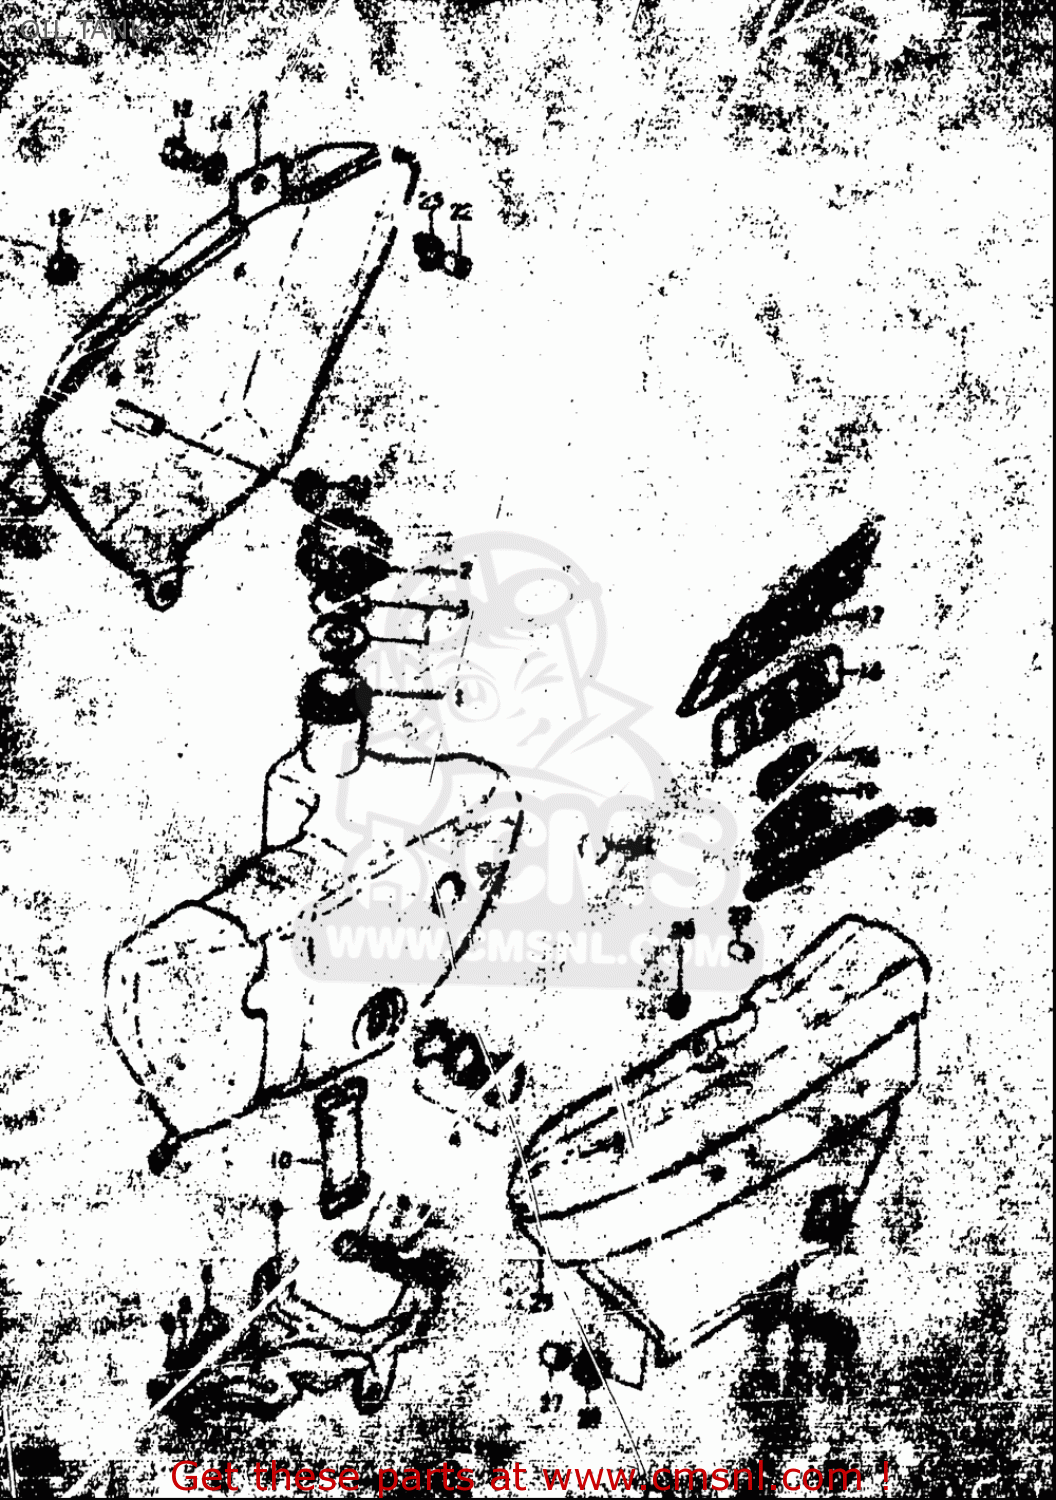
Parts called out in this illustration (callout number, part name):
2	CAP,OIL TANK
4	LENS SET,OIL LEVEL
6	BOLT
7	BOLT
8	WASHER
9	WASHER,LOCK
10	BAND
11	CUSHION
13	SCREW
14	WASHER
20	NUT
22	SPACER(6X9.8X6)
23	CUSHION
26	EMBLEM,CCIS
28	CUSHION
29	CUSHION
